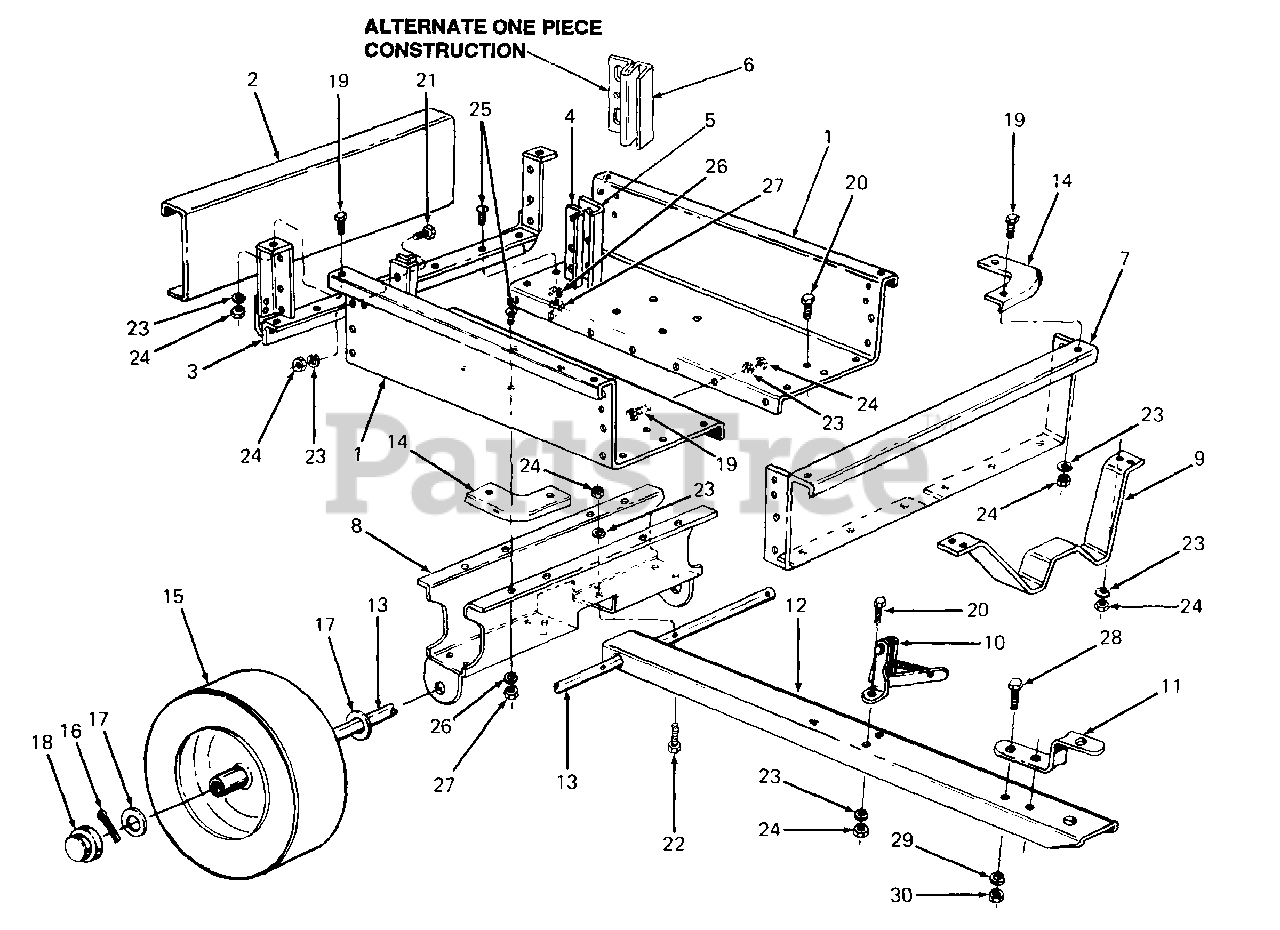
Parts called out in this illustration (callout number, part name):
5	Guide, Tailgate - Outside
6	Guide, Tailgate - One Piece 2
17	Washer, Flat, 1.03 ID
18	Hub Cap
19	Screw, Hex Cap, 1/4-20 X .50 Lg
20	Screw, Hex Cap, 1/4-20 X .62 Lg
21	Screw, Hex Cap, 1/4-20 X .75 Lg
22	Screw, Hex Cap, 1/4-20 X 1.75 Lg
23	Washer, Lock, 1/4
24	Nut, Hex, 1/4-20
25	Screw, Truss Hd, 5/16-18 X .75 Lg 14
26	Washer, Lock, 5/16
27	Nut, Hex, 5/16-18
28	Screw, Hex Cap, 3/8-16 X 1.0 Lg
29	Washer, Lock, 3/8
30	Nut, Hex, 3/8-16
